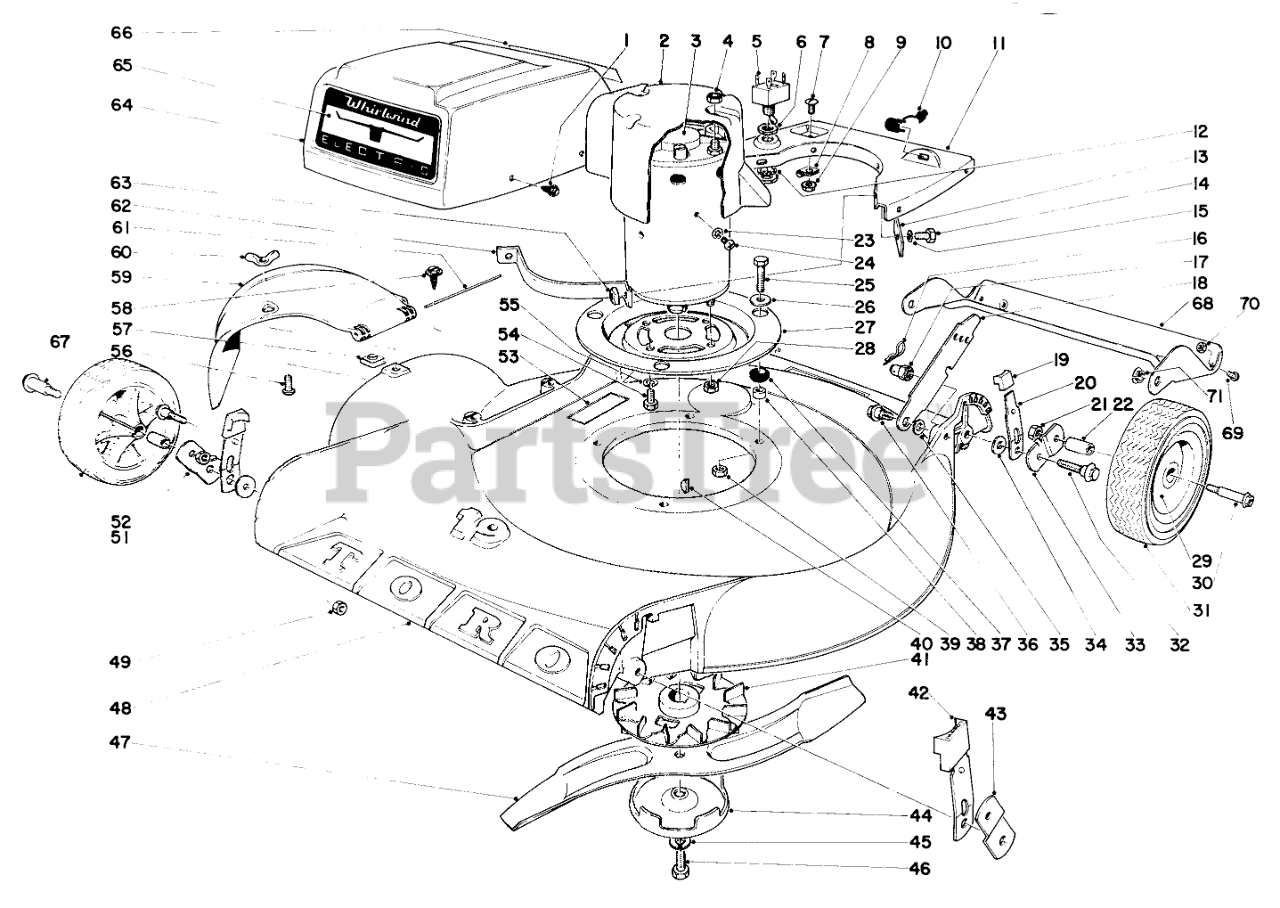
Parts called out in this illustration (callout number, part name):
1	SCREW-HWHTF
2	Cover-Switch & Motor
3	Motor
5	Switch
7	10-24 X 5/8 PAN HD MS
8	3/16 SUPPORT
9	NUT-KEPS
10	Strain Relief
11	Support Shroud
12	Lockwasher
13	Washer Support
14	SCREW-HH
15	WASHER-LOCK/EXT
16	PIN-COTTER, HAIR
17	Nut
18	Latch
20	Spring Arm
21	Nut
22	Bushing
23	WASHER-LOCK/INT
25	SCREW-HH
26	WASHER-FLAT
27	Motor Support Plate
28	Nut
29	Wheel Assy. (Incl. Ref. No. 22)
30	Wheel Bolt
31	8 TIRE
32	Pivot Screw
33	Pivot Arm
34	WASHER-PIVOT
35	SPACER
36	SCREW-SHOULDER
37	GROMMET
38	Spacer
39	Nut
40	KEY-WOODRUFF
41	Fan & Blade Retainer
42	ARM KNOB
43	Pivot Arm
44	Scalp Cup
45	WASHER-LOCK
46	SPECIAL SCREW
47	Blade
48	Housing
49	Nut
52	Pivot Arm
53	Decal
54	SCREW-HH
55	WASHER-LOCK, INTERNAL
57	NUT-SPEED
58	SCREW-HWHTF
59	Deflector
60	NUT-WING SPECL
61	HINGE PIN
62	Clamp-Shroud Support
63	NUT-SQUARE
64	Shroud
65	Decal-Whirlwind
66	Decal
66	Decal (Canadian)
68	Rear Safety Shield
69	Screw-Nylon
70	NUT-JAM
71	Nyliner
